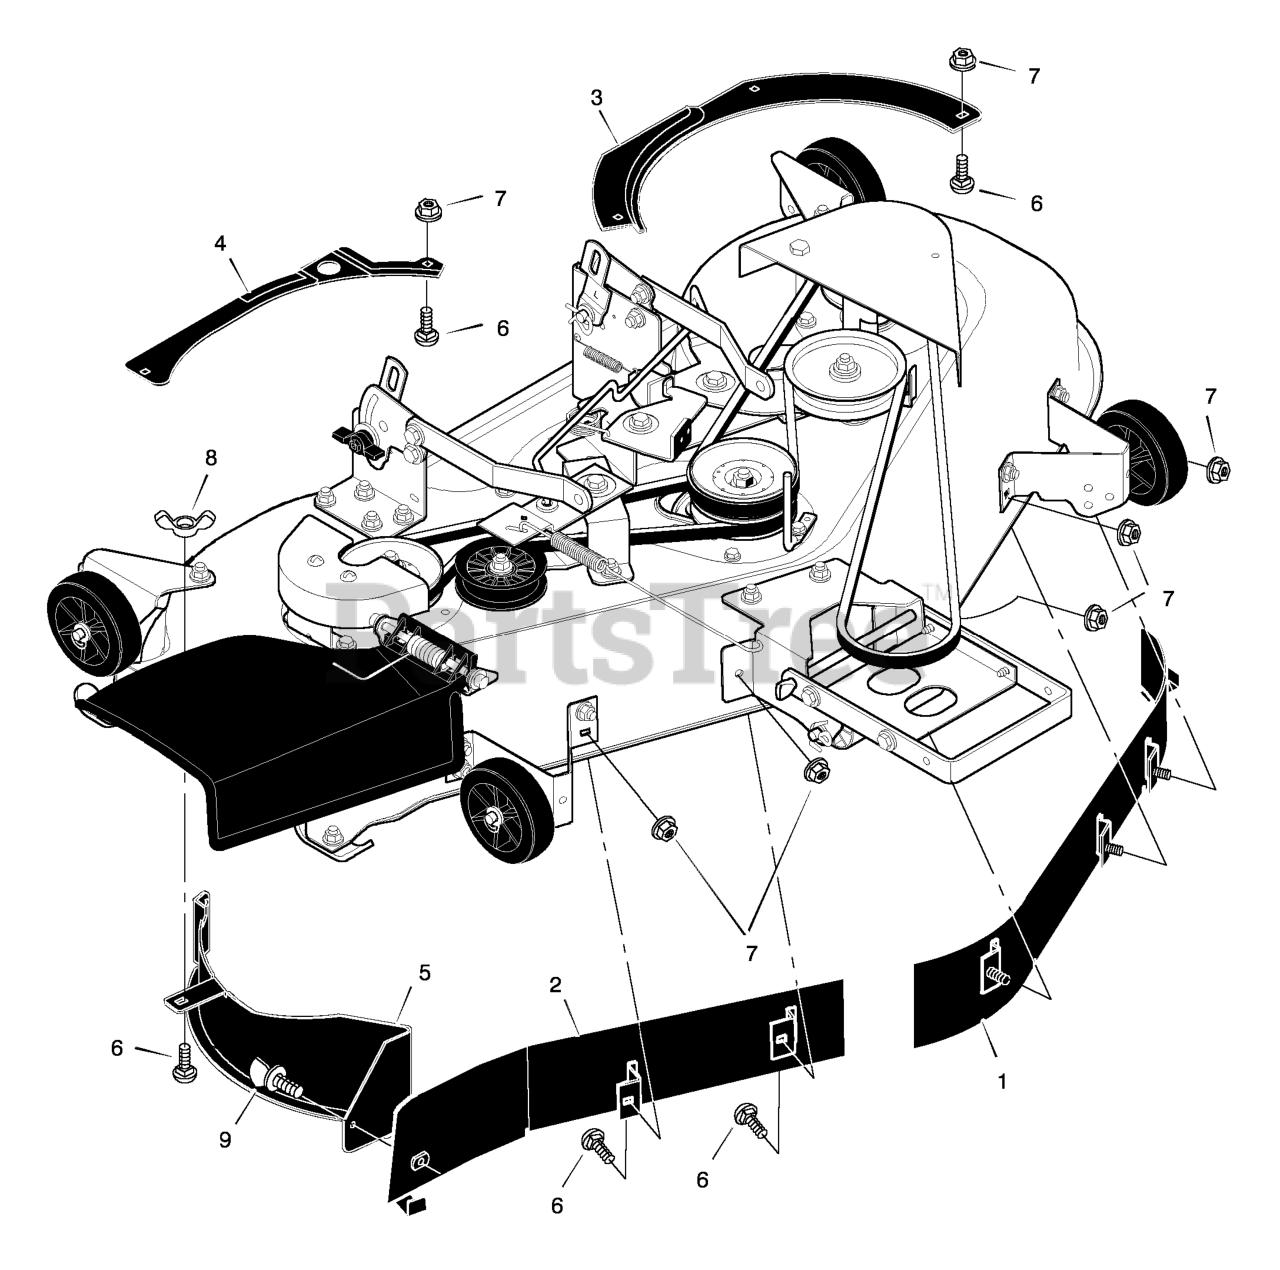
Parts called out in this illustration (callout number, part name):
1	Baffle, Left Front
2	Baffle, Right Front
3	Baffle, Left Rear
4	Baffle, Right Rear
5	Plate, Mulcher
6	Bolt, Carriage
7	Nut, Flange
8	Wingnut
9	Screw, Thumb
